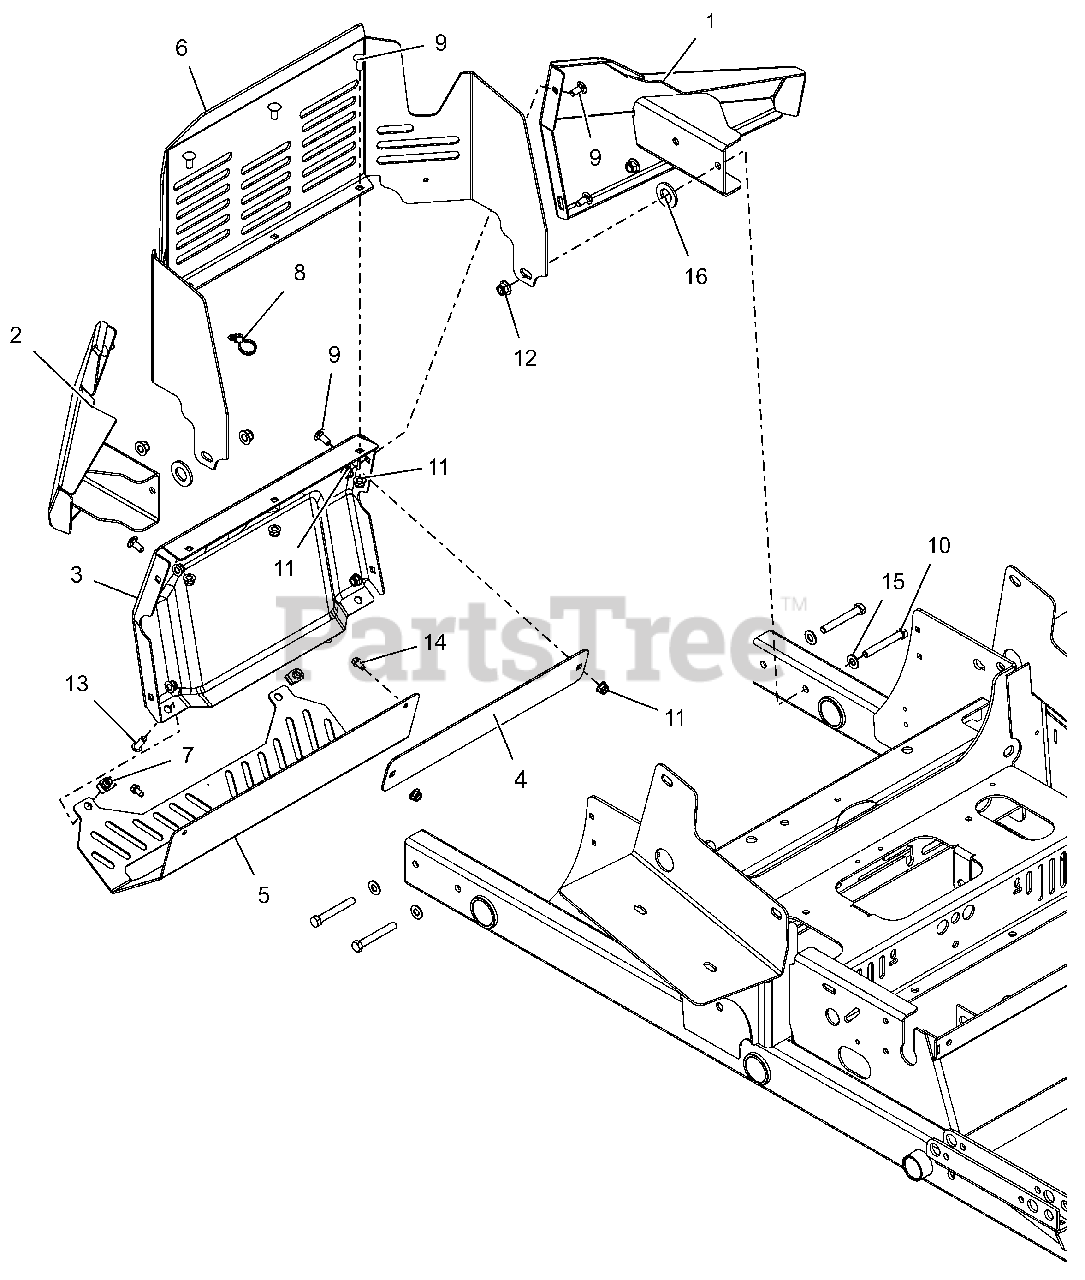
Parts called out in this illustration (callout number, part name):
1	WMT,LH REAR BMPR WING W/DECAL
2	WMT,RH REAR BMPR WING W/DECAL
3	PT200/400 REAR BUMPER - BLACK
4	BACKER PLATE - RED
5	PT200/400 MUFFLER GUARD - BLK
6	PT200 ENGINE GUARD - RED
7	NUT-CLIP RETAINER 5/16-18X.56
8	CABLE TIE W/ TREE (.25 HOLE)
9	@BLT-RDHDSQNK .31-18X.75 G5YZ
10	@BLT-HEX .38-16X2.75 GR5 YWZC
11	@NUT-LK-NYL-FLG .31-18 YWZC
12	@NUT-LK-NYL-FLG .38-16 YWZC
13	SCR-SKH .31-18X1.0 BTNHD YWZC
14	SCR-TAP .25-20X.50 HWH TR YWZ
15	@WSHR-FL-STL.406X.812X.065 YWZ
16	@WSHR-FL-STL.812X1.50X.135YWZC
